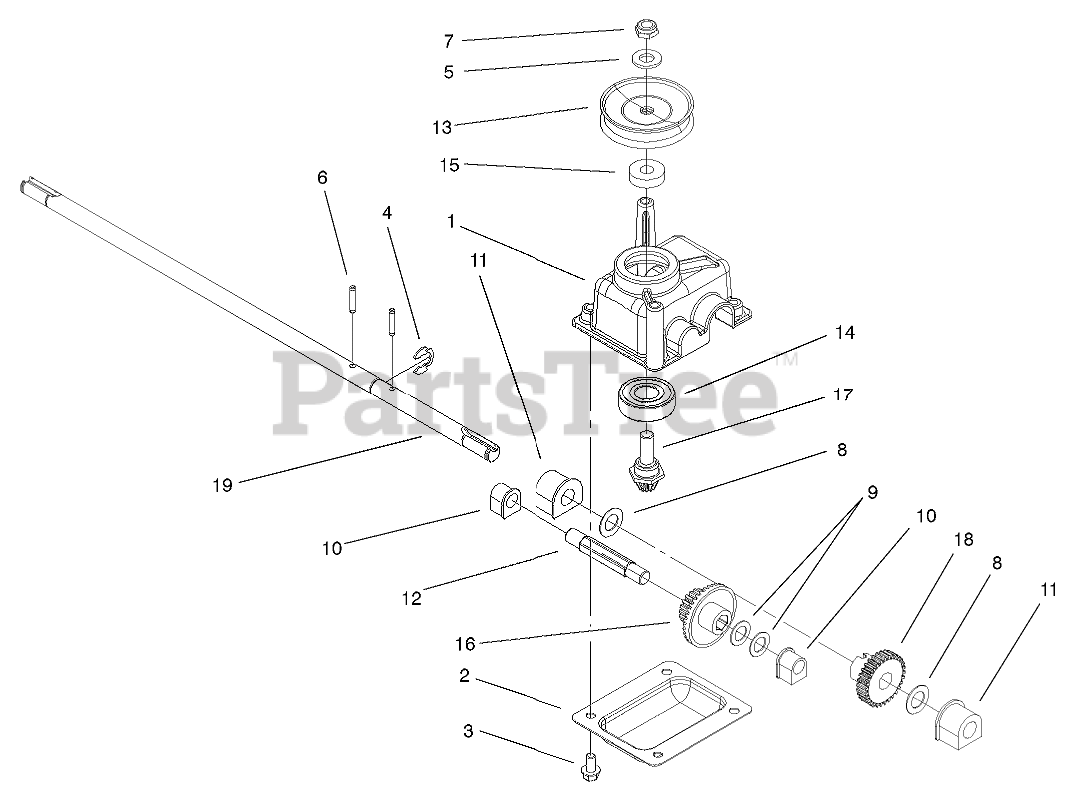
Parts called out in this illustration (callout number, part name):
1	CASE-GEAR
2	COVER-CASE, GEAR
3	SCREW-HWH
4	RING-RETAINING
5	WASHER-FLAT
6	PIN-GROOVE
7	NUT-HEX
8	WASHER-PLAIN
9	WASHER-THRUST
10	BUSHING
11	BUSHING
12	SHAFT-INTERMEDIATE
13	PULLEY-HALF
14	BEARING-BALL
15	SPACER
16	GEAR-15T SPUR, 37T BEVEL
17	GEAR-PINION, BEVEL
19	SHAFT-OUTPUT
